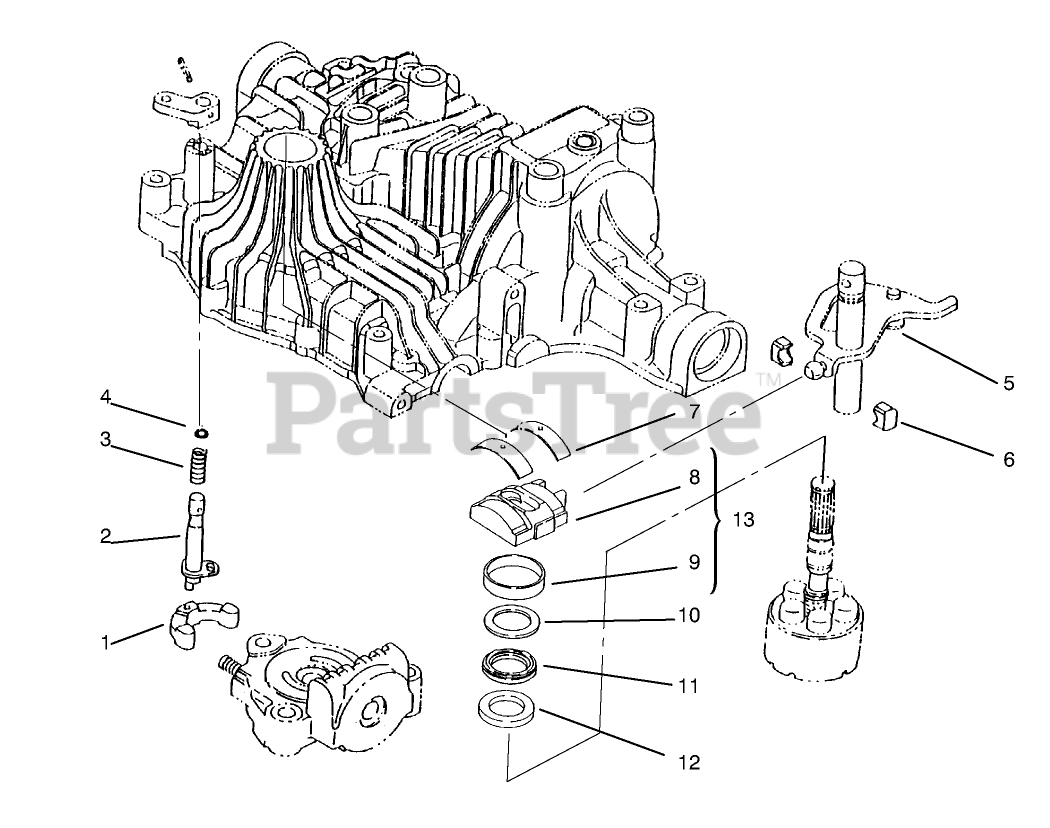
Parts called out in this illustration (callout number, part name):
2	SHAFT-BYPASS
3	SPRING
4	O-RING
5	BLOCK ASM
6	Block-Shift
7	THRUST METAL
8	Plate-Swash
9	Bushing-Swashplate
10	PLATE-THRUST
11	BEARING
12	PLATE - THRUST
13	PLATE-SWASH
